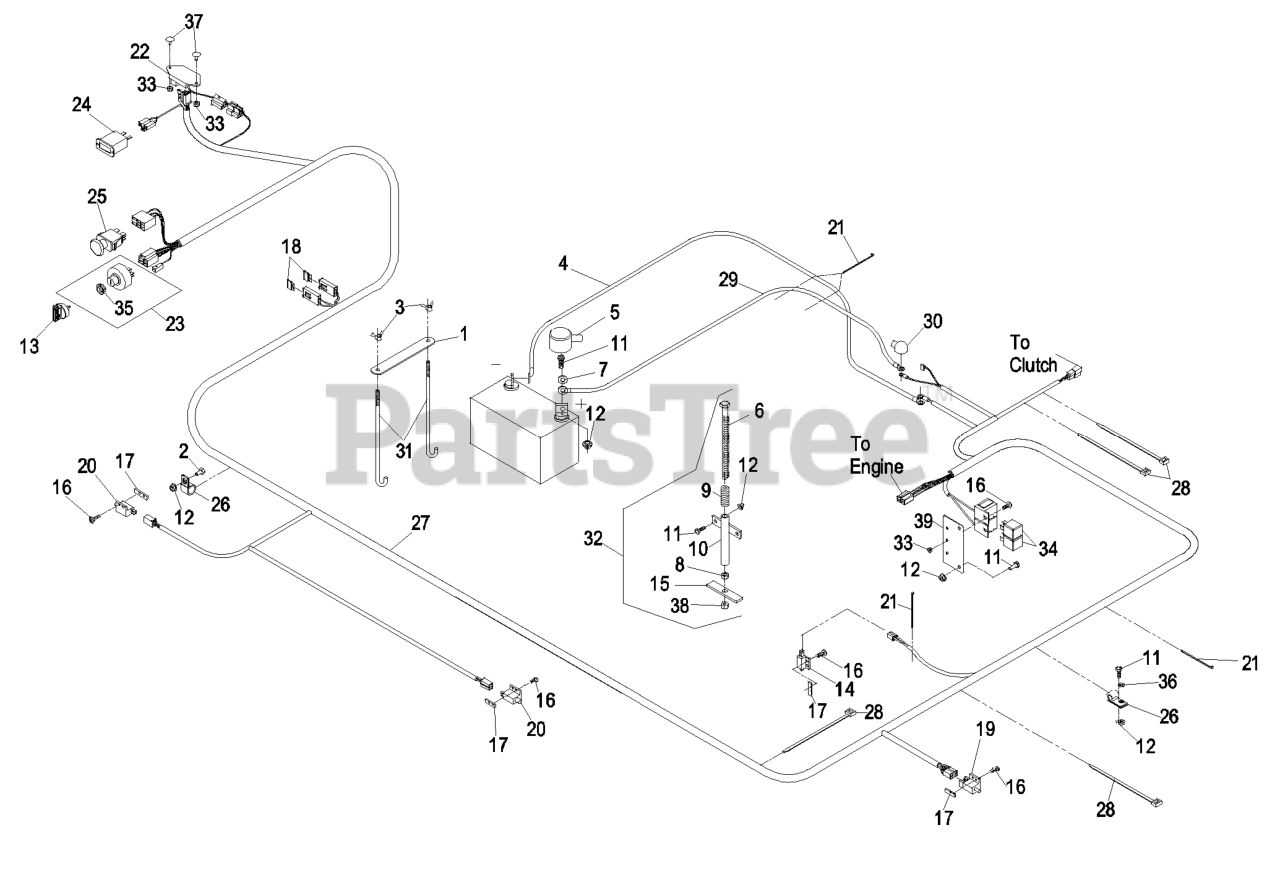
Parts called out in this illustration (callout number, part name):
1	STRAP-HOLDDOWN, BATTERY
2	SCREW-HH
3	WINGNUT
4	WIRE-GROUND
5	INSULATOR-BATTERY
6	SCREW-HH
7	WASHER-FLAT
8	NUT-HEX
9	SPRING-SWITCH, SEAT
10	MOUNT-SPRING, SEAT
11	SCREW-HH
13	KEY-IGNITION
14	SWITCH-CLOSED, NORMALLY
15	PLATE-SWITCH, SEAT
16	SCREW-PPH
17	PLATE-TAPPED
18	FUSE-BLADE TYPE, 20 AMP
20	SWITCH-OPEN, NORMALLY
21	TIE-CABLE
22	MODULE-DELAY, SEAT
23	ASM,SWITCH W/NUT
24	METER-HOUR
25	SWITCH-PTO
26	CLIP-LOOM
27	HARNESS, WIRE LAZER KC
28	TIE-PLASTIC
29	POSITIVE BATTERY CABLE AS
30	INSULATOR-SOLENOID
31	BOLT-HOLDDOWN
32	ASM,SEAT SWITCH ACTUATOR
33	NUT-LOCK, NI
35	NUT-SWITCH, IGNITION
36	WASHER-FLAT
37	BOLT-CARR
38	NUT-LOCK, NI
39	MOUNT-RELAY
